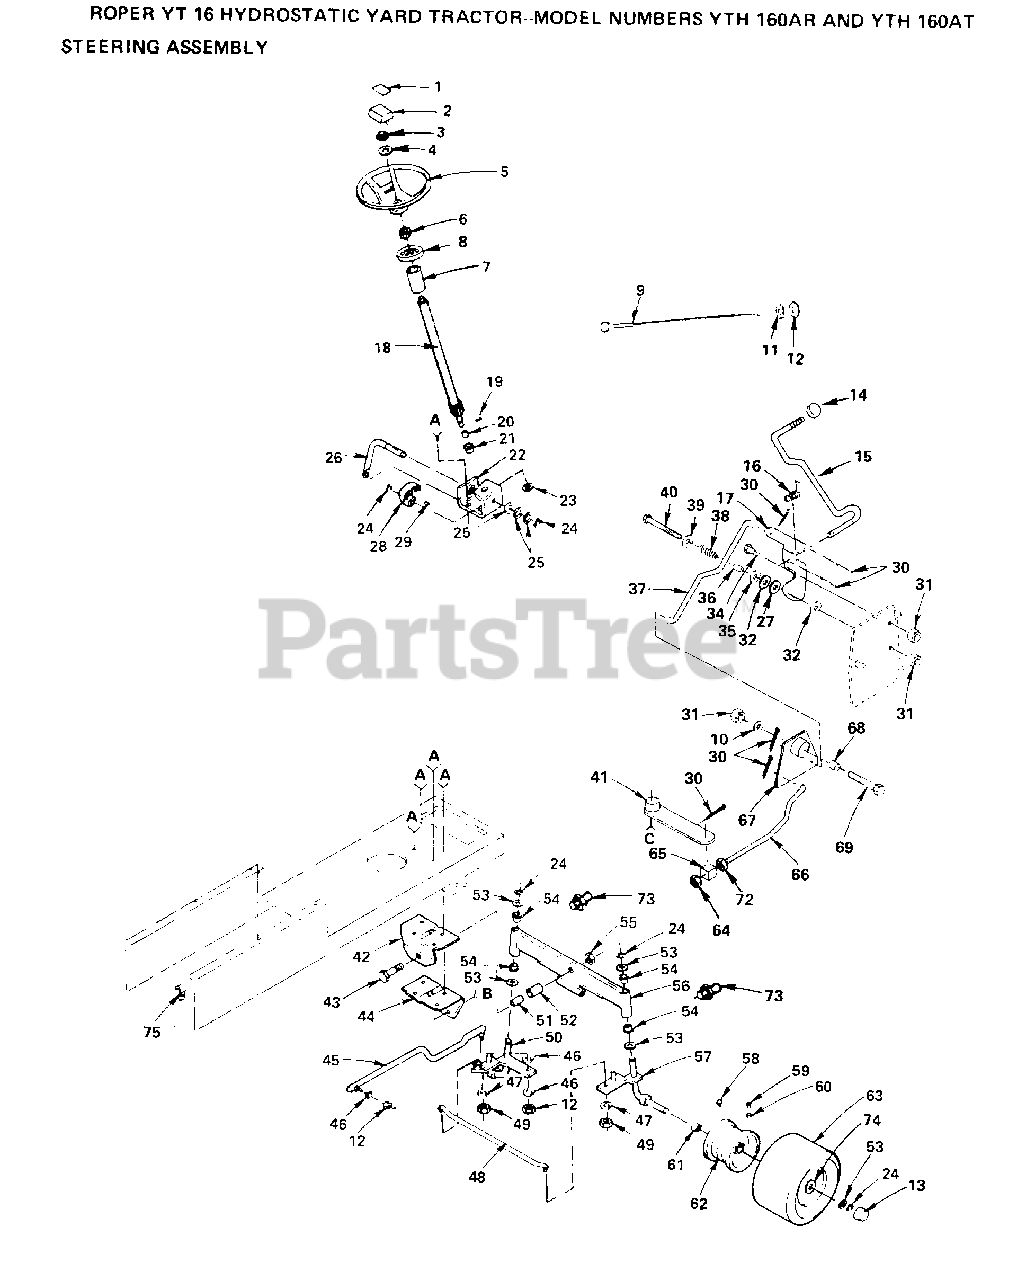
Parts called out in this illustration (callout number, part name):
1	DECAL - STEERING WHEEL
2	INSERT-WHEEL LT
3	NUT
4	WASHER
6	ADAPTER LT
10	WASHER
11	LOCKWASHER
13	HUB CAP
14	KNOB T (1/2-HOLE)
17	BRKT CONTROL HYT
20	SHAFT SPACER LT
21	BUSHING
23	WASHER D
24	RING
25	WASHER .T
26	ROD-STEERING T
27	WASHER HYT
28	GEAR-SECTOR T
29	KEY-WOODRUFF LT
30	COTTER PIN
32	WASHER FRIC HYT
34	BOLT HYT
35	WASHER D
36	SPACER HYT
37	LINK CONTROL HY
38	SPRING HYT
39	WASHER
40	BOLT - HEX 3/8 - 16 X 3
41	ARM ASSEM HYT
42	SUPPORT-SADDL T
43	BOLT LT
44	SUPPORT.SADDLE.FT
45	LINK-DRAG LT
46	LOCKWASHER
47	LOCKWASHER
49	NUT
50	SPINDLE LH YT
54	COL. SRTG. BEAR.
55	"NUT-LOC,FLANGE LT"
56	FRONT AXLE
58	FITTING LT
59	VALVE STEM LT
60	VALVE CAP
61	"FLANGE, BEARING"
64	NUT
65	TRUNION HYT
66	ROD-ADJ. CONTROL
67	"HYT, BELLCRANK"
72	LOCKNUT
73	ZERK M
75	INSUL CLIP T
